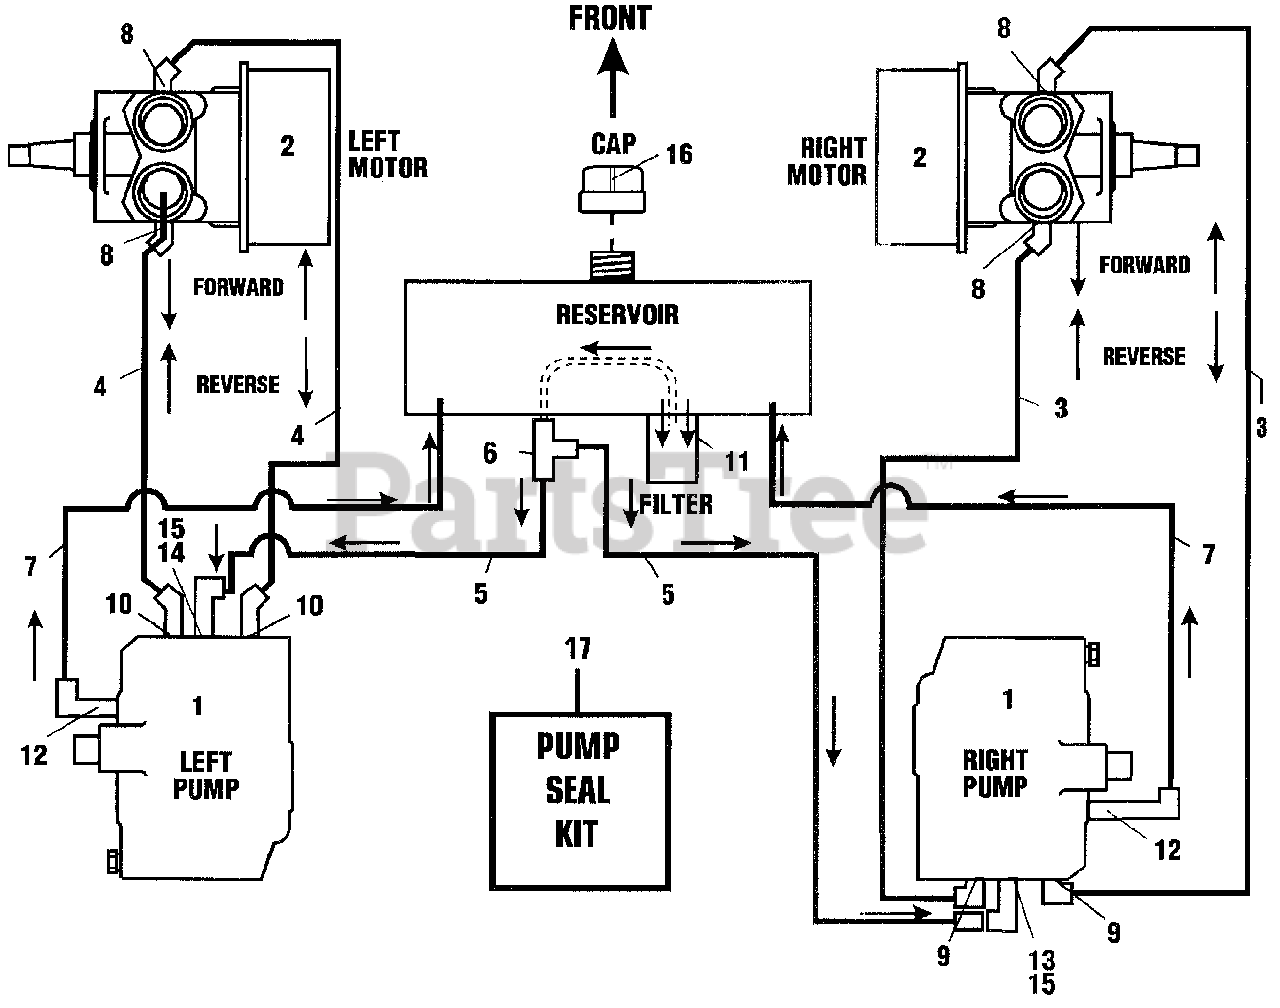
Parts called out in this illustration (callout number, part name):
1	PUMP ASSY., HYDRAULIC
2	MOTOR ASSY., HYDRAULIC
3	HOSE ASSY., R. MOTOR
4	HOSE ASSY., L. MOTOR (NOT AVAILABLE)
5	HOSE ASSY., PUMP
6	ADAPTER, TANK SUPPLY HOSE
7	HOSE ASSY., PUMP RETURN
8	ADAPTERM MOTOR-HOSE
9	ADAPTER, R. PUMP MOTOR
10	ADAPTER, L. PUMP MOTOR
11	FILTER, HYDRAULIC
12	ADAPTER, PUMP CASE
13	ADAPTER, R. PUMP CHARGE
14	ADAPTER, L. PUMP CHARGE
15	ADAPTER, PUMP CHARGE HOSE
16	CAP ASSY., RESERVOIR
17	SEAL KIT, PUMP
